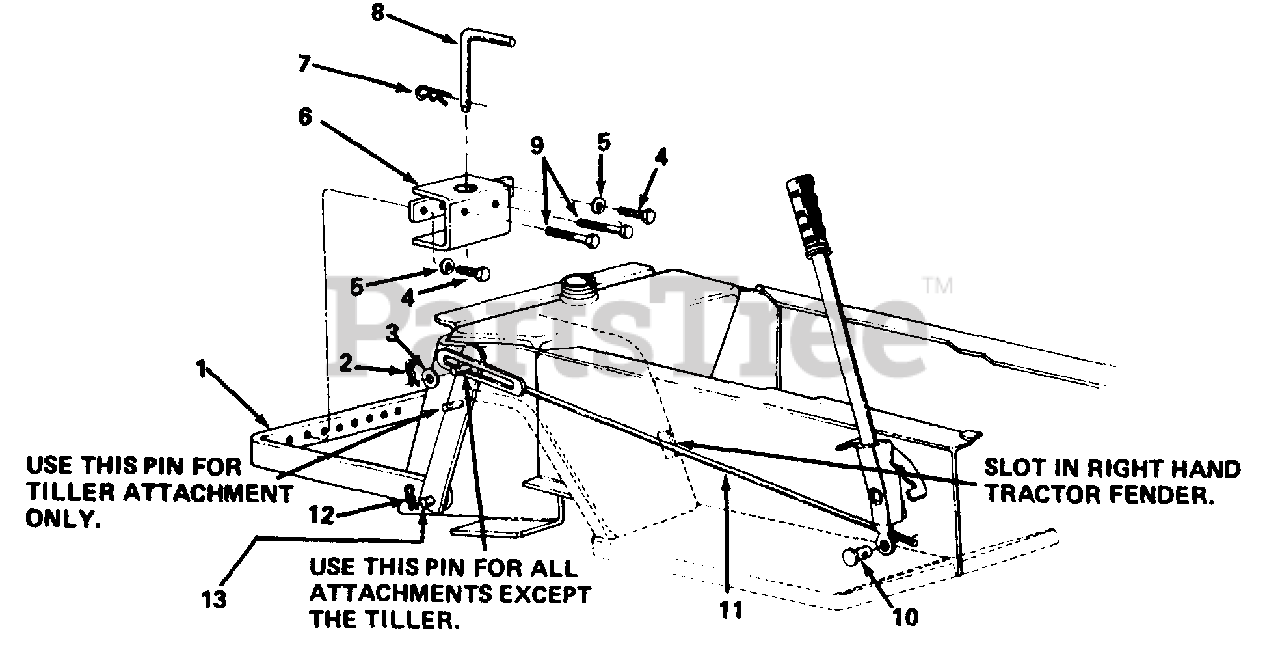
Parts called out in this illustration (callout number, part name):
3	Fl-Wash. 1/2" I.D.
4	Hex Bolt 1/2-13 x 1.0" Lg.
5	L-Wash. 1/2" I.D.
9	Hex Bolt 1/2-13 x 3.0" Lg.
10	Adjustment Ferrule
